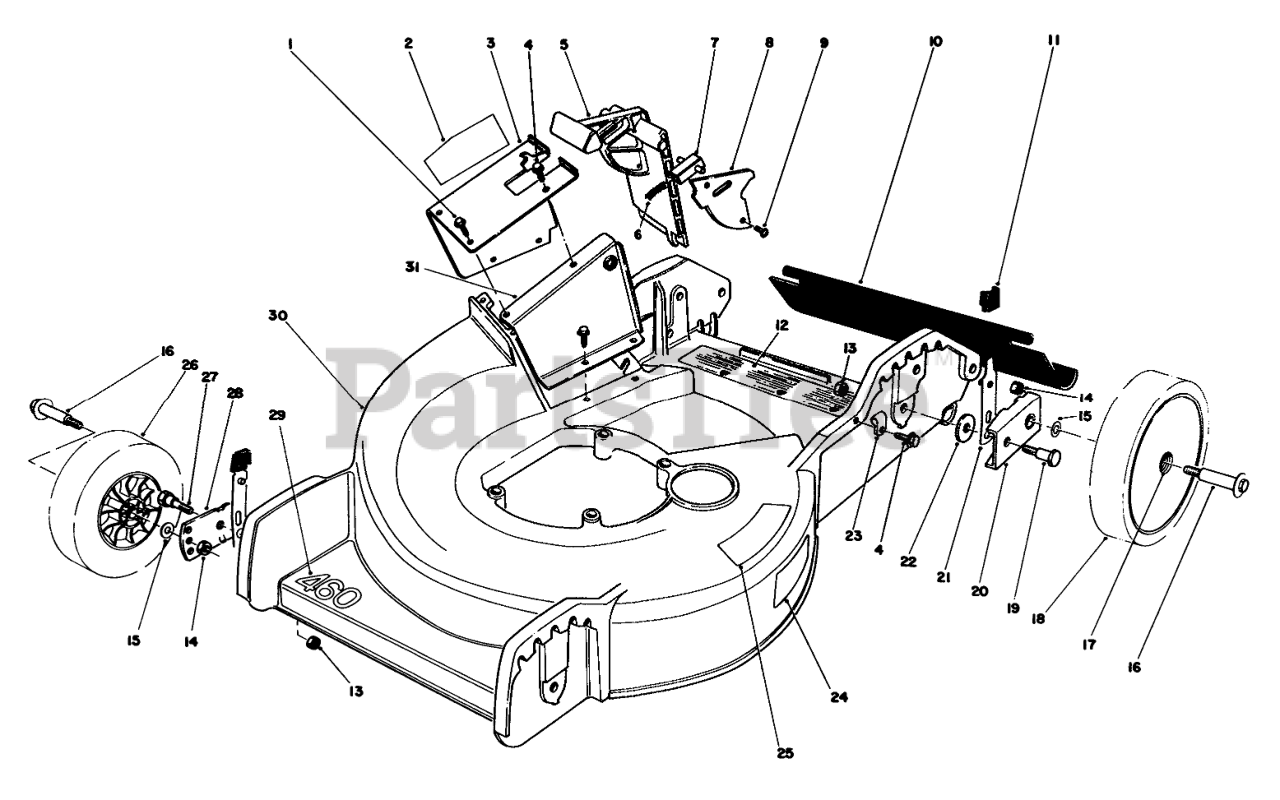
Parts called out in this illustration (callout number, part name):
1	SCREW
2	OBS DANGER DECAL FR/E/GER
3	Tunnel-Outer (Incl. Ref. #2)
4	SCREW
5	Door Mulching
6	SPRING-COMPRESSION, LATCH
7	Door Latch
8	Cover Door
10	SHIELD - TRAILING
11	KNOB-ARM
12	DECAL-DANGER
13	NUT-LOCK, NI
14	Nut
15	WASHER
16	Bolt-Wheel
17	BUSHING
18	Wheel & Tire Assembly (Incl. Ref. #17)
19	PIVOT SCREW
20	HP PIVOT ARM ASM
21	SPRING ARM ASM
22	PIVOT WASHER
23	CLAMP-CABLE
24	Decal-Place Foot Here
25	STEP PAD DECAL
26	Wheel & Tire Assembly (Incl. Ref. #17)
27	PIVOT SCREW
28	PIVOT ARM ASSY
29	Decal-460
30	Housing
31	Tunnel-Inner
